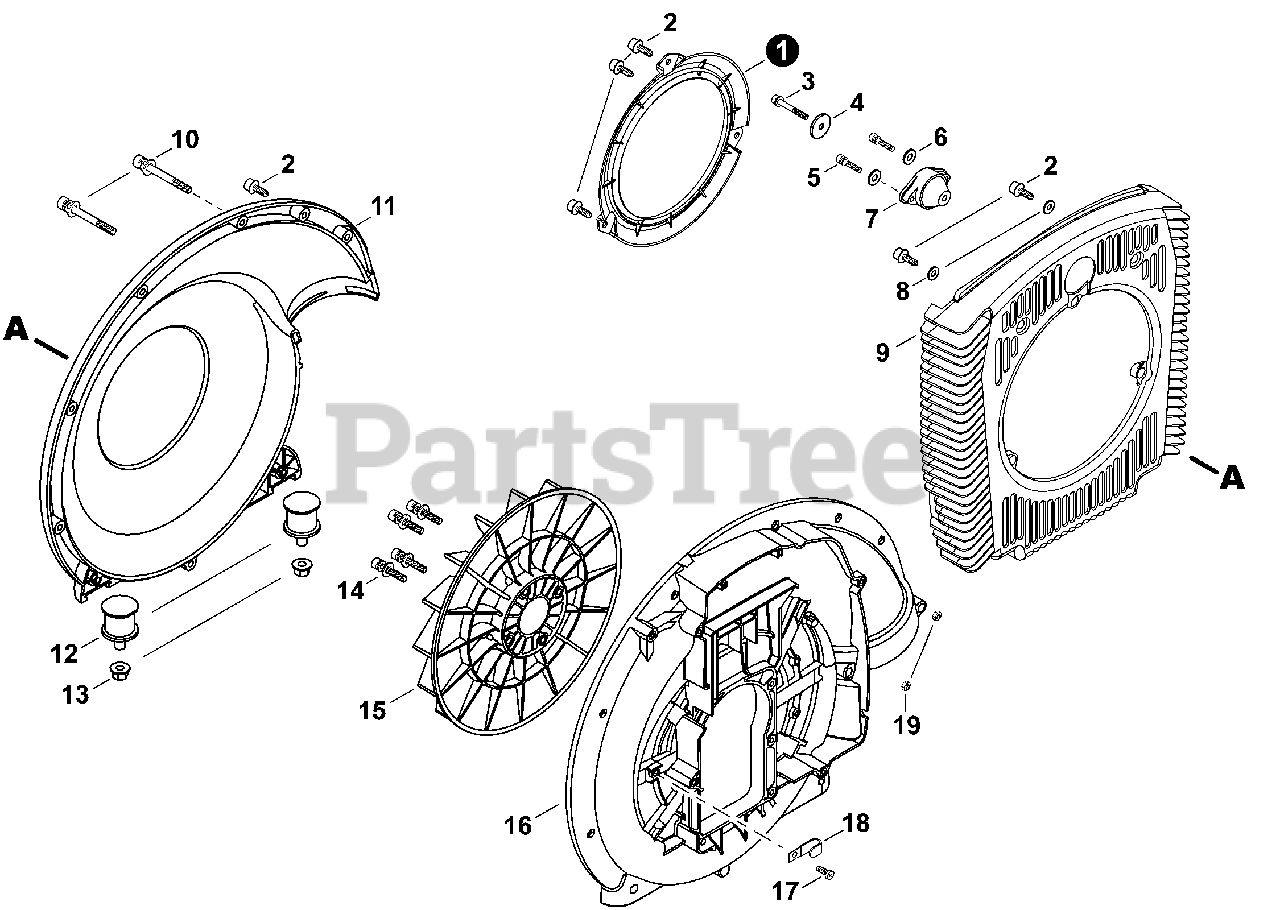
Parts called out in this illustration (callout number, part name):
1	COVER, LEAF GUARD
2	BOLT M5×20
3	BOLT TAPPING M5
4	WASHER Ø25ר5.5×2
5	BOLT 5×16
6	WASHER 5
7	CUSHION, AV 5
8	WASHER 5.5×12×0.8
9	COVER, INTAKE
10	BOLT M5×70
11	COVER, FAN
12	CUSHION, AV 6
13	NUT, FLANGE M6
16	CASE, FAN
17	SCREW, TAPPING 5×14
